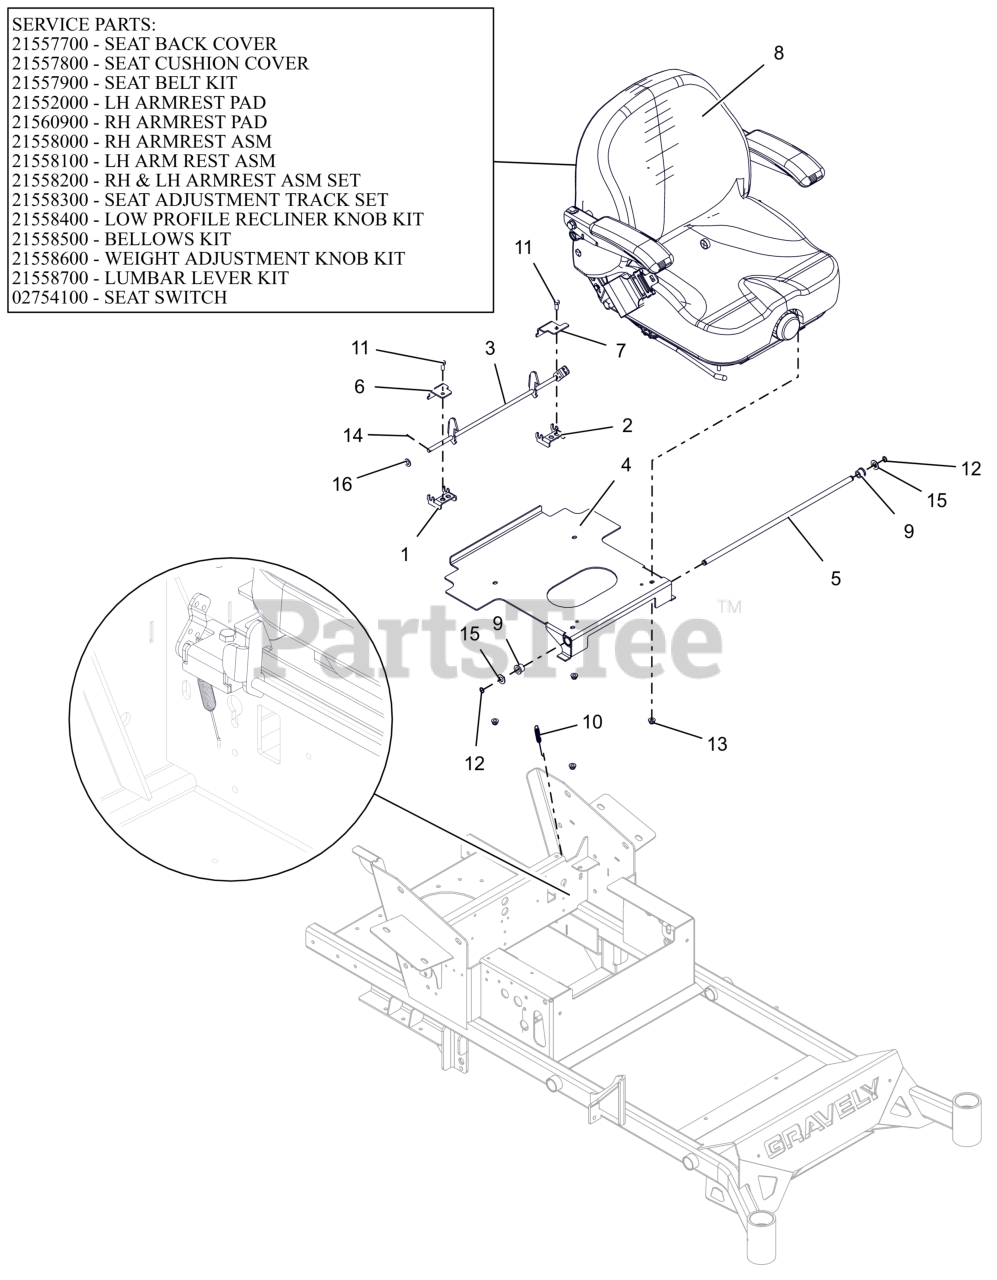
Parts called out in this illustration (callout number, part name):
1	PT100 RH SEAT LATCH MNT WMT-BL
2	PT100 LH SEAT LATCH MNT WMT-BL
3	PT100 SEAT LATCH WLDMT - BLACK
4	PT100 SEAT PLATE WLDMT - BLACK
5	SHAFT, PT100 SEAT PIVOT
6	PT100 RH TOP SEAT LATCH MNT-BL
7	PT100 LH TOP SEAT LATCH MNT-BL
8	SEAT, FULL SUSPENSION
8	COVER, SEAT BACK
8	COVER,SEAT CUSHION
8	KIT, SEAT BELT
8	PAD, ARMREST LH
8	PAD, ARMREST RH OR LH (HARD)
8	ARMREST, RH ASSEMBLY
8	ARMREST, LH ASSEMBLY
8	SET, RH & LH ARMREST ASSEMBLY
8	SET, SEAT ADJUSTMENT TRACK
8	KIT, LOW PROFILE RECLINER KNOB
8	KIT, BELLOWS
8	KIT, WEIGHT ADJUSTMENT KNOB
8	KIT, LUMBAR LEVER
8	SWITCH- SNAP MTG N.O.
9	BSHG, FLG .516X.750X.625X.937
10	SG-TENS .043X.44X3.31 WLD 5.8
11	BLT,HEX .31-18X.75 G5 ZCC
12	RG-RTNG-EXT .500X.050 (SNAP)
13	NUT,NYL-FLG .31-18 GF ZCC
14	PIN, CTR .09X.750 EXTPRSQCT ZC120
15	WSHR, FLT .531X1.00X.063 ZCC
16	WSHR,FLT .406X.812X.065 ZCC
